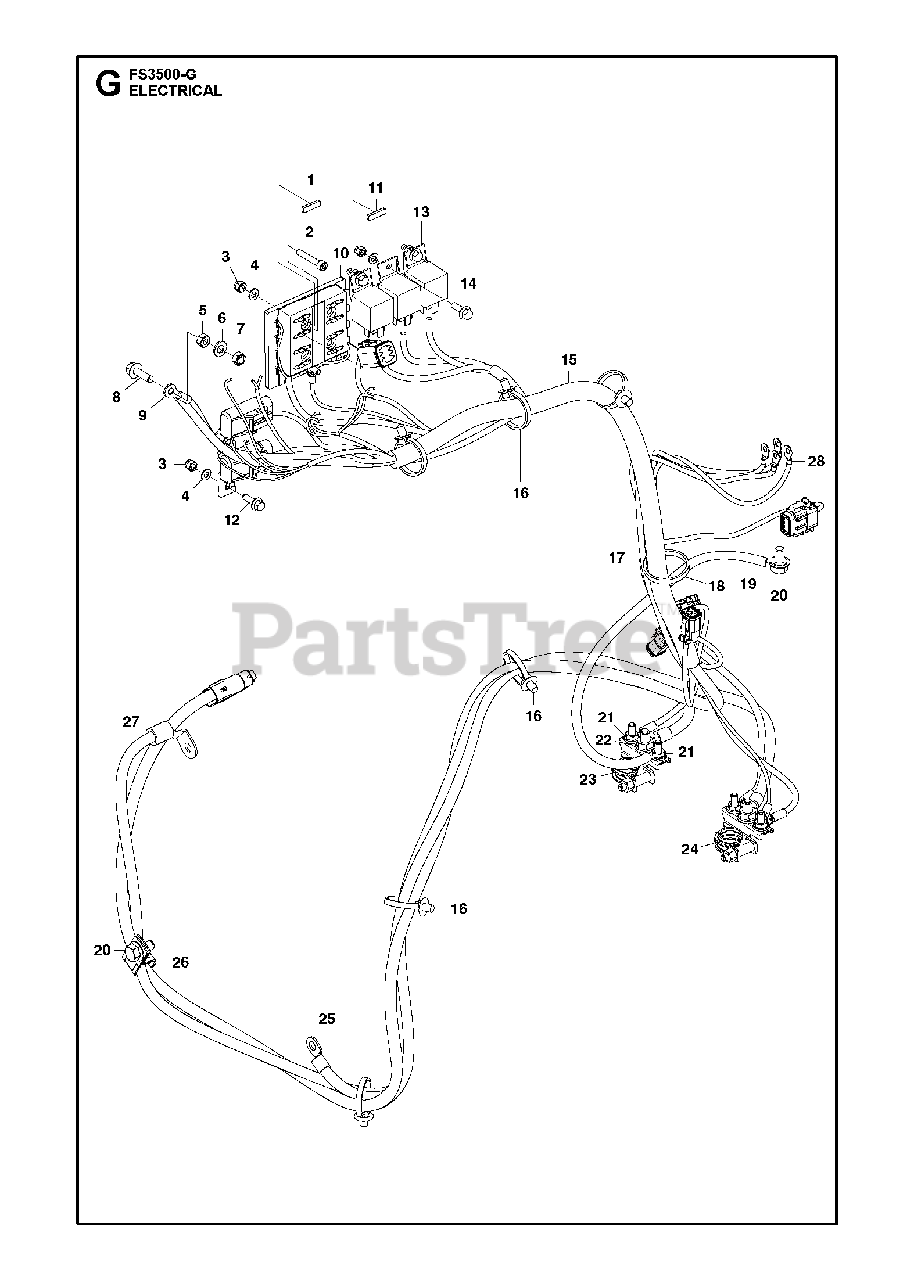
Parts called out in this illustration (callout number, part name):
2	SCREW IHSCM
3	HEXAGON LOCKING NUT
4	WASHER
7	HEXAGON LOCKING NUT
9	CABLEBattery Ground 900 mm
19	CABLEBattery Negative 600 mm
21	HEXAGON NUT FLANGE
22	HEXAGON NUT FLANGE
25	CABLEBattery Negative 850 mm
